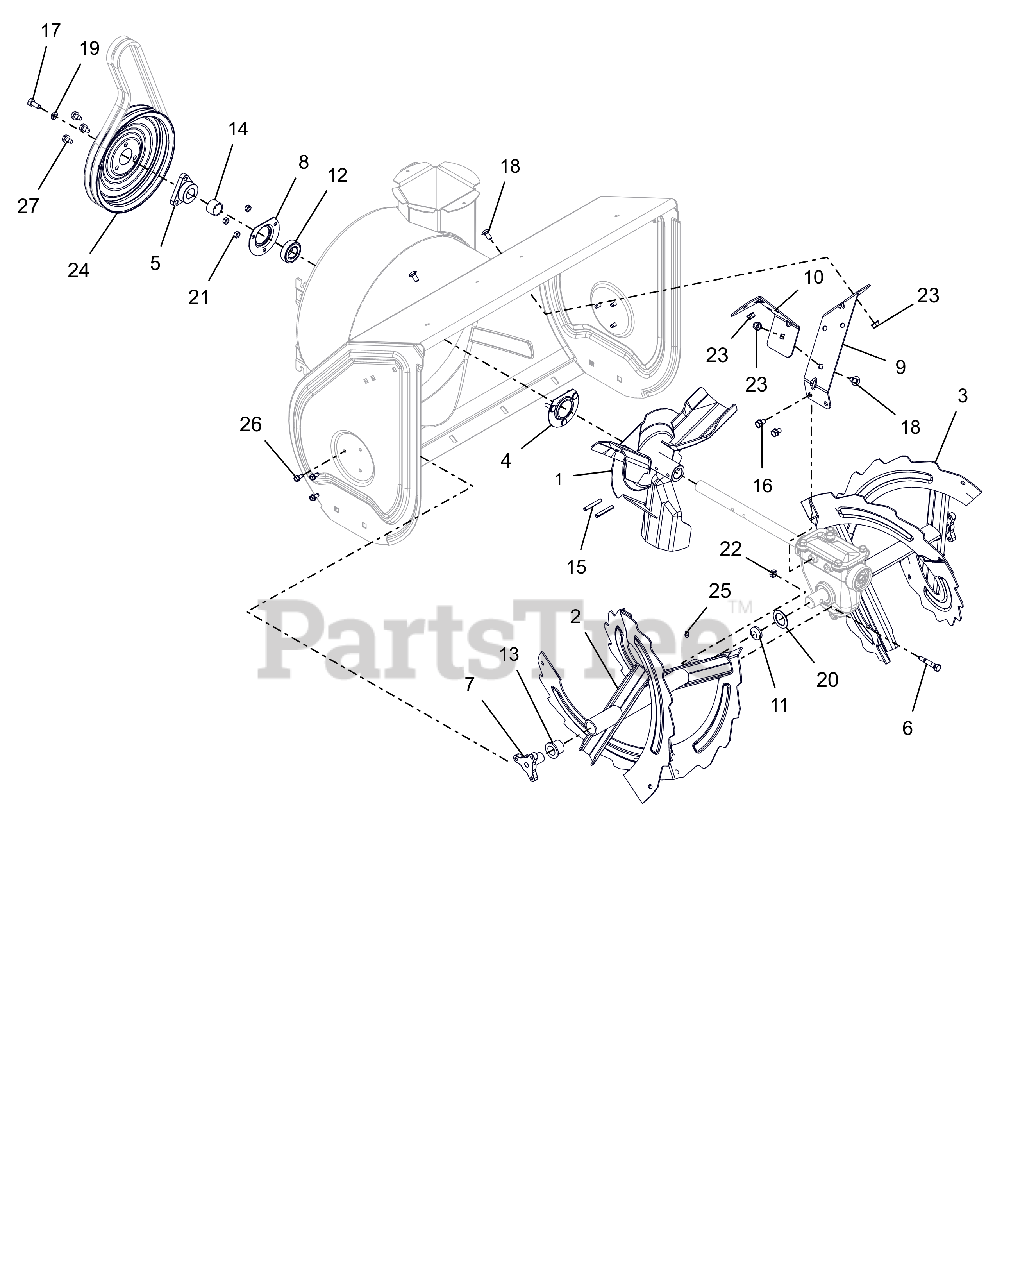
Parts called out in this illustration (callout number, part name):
1	IMPELLER, 3 BLADE-14"
2	RAKE, RH W/ZERK - 28"
3	RAKE, LH W/ZERK - 28"
4	BEARING FLANGE
5	PULLEY HUB, D-BORE .87 PRO
6	SHEAR BOLT SERVICE ASSEMBLY
7	SUPPORT, RAKE BUSHING
8	BEARING FLANGE
9	BRACKET, GEARCASE SUPPORT - LH
10	BRACKET, GEARCASE SUPPORT - RH
11	PLUG, RAKE TUBE
12	BRG-BALL .876X1.75X.50 RSTFP
13	BSHG-FLG, NY.778 ID X 1.018 OD
14	BSHG,SPCR .895X1.065X.693
15	PIN-ROLL .250X1.75
16	BLT, SEMS .31-18X.50 G5 ZCC
17	BLT, HEX .31-24X.750 G5 ZCC
18	BLT,RHSSN.31-18X.625 G5 ZCCP30
19	WSHR, LK-HVY .312X.097 ZCC
20	WSHR, FLT 1.010X1.505X.062 ZCC
21	NUT,LK-CTR .25-20 GA ZCC
22	NUT,LK-CTR .31-18 GA ZCC
23	NUT-LK-TOP-FLG .312-18 GF ZCC
24	PULLEY, SPIN FORM DUAL GROOVE
25	ZERK,FITTING .25X.125 DRIVE IN
26	SCR-TAP .25-20X.50 HWH ZCC
27	SCR,TAP .312-18X.50 HWH TR ZCC
